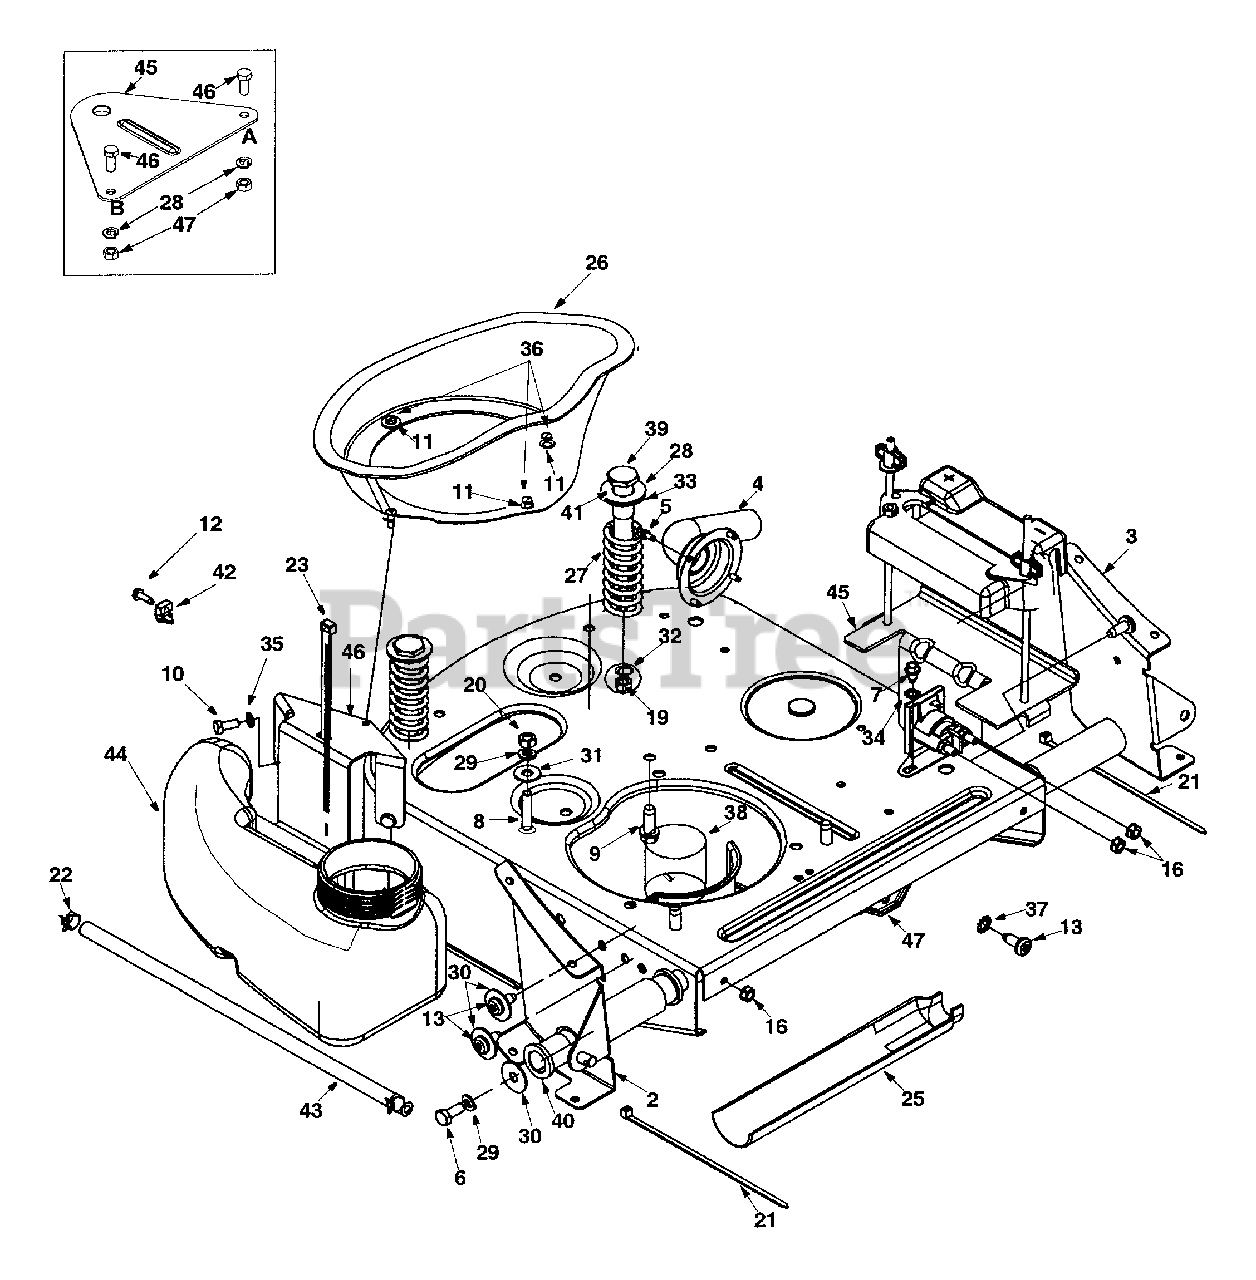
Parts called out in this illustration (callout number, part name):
5	Hex Fl. Screw #8-32 x 0.375
6	Hex Screw 5/16-24 x .75" Gr.5
7	Self-Tapping Screw
8	Hex Screw 5/16-24 x 1.5" Gr.5
9	TT Screw 3/8-16 x 1.0"
10	Hex Screw 1/4-20 x 0.5"
11	Hex Slot Sems Screw #10-32 x 0.38
12	TT Screw #10-32 x 0.625"
13	TT Screw 5/16-18 x 0.75"
16	Hex Sems Nut 1/4-20
19	Hex Nut
20	Hex Nut 5/16-24 Gr.5
21	Cable Tie
22	Hose Clamp
23	Cable Tie
25	Oil Drain Sleeve
26	Engine Duct
27	Compression Spring
28	Rubber Washer
29	Lock Washer
30	Flat Washer
31	5/16 Washer
32	Lock Washer
33	Flat Washer
34	Lock Washer
35	Lock Washer
36	Flat Washer
37	Lock Washer
38	Motor Oil
39	Shoulder Screw
40	Flange Bearing
41	Flange Bearing
42	Throttle Casing Clamp
43	Fuel Line Hose
44	Fuel Tank
